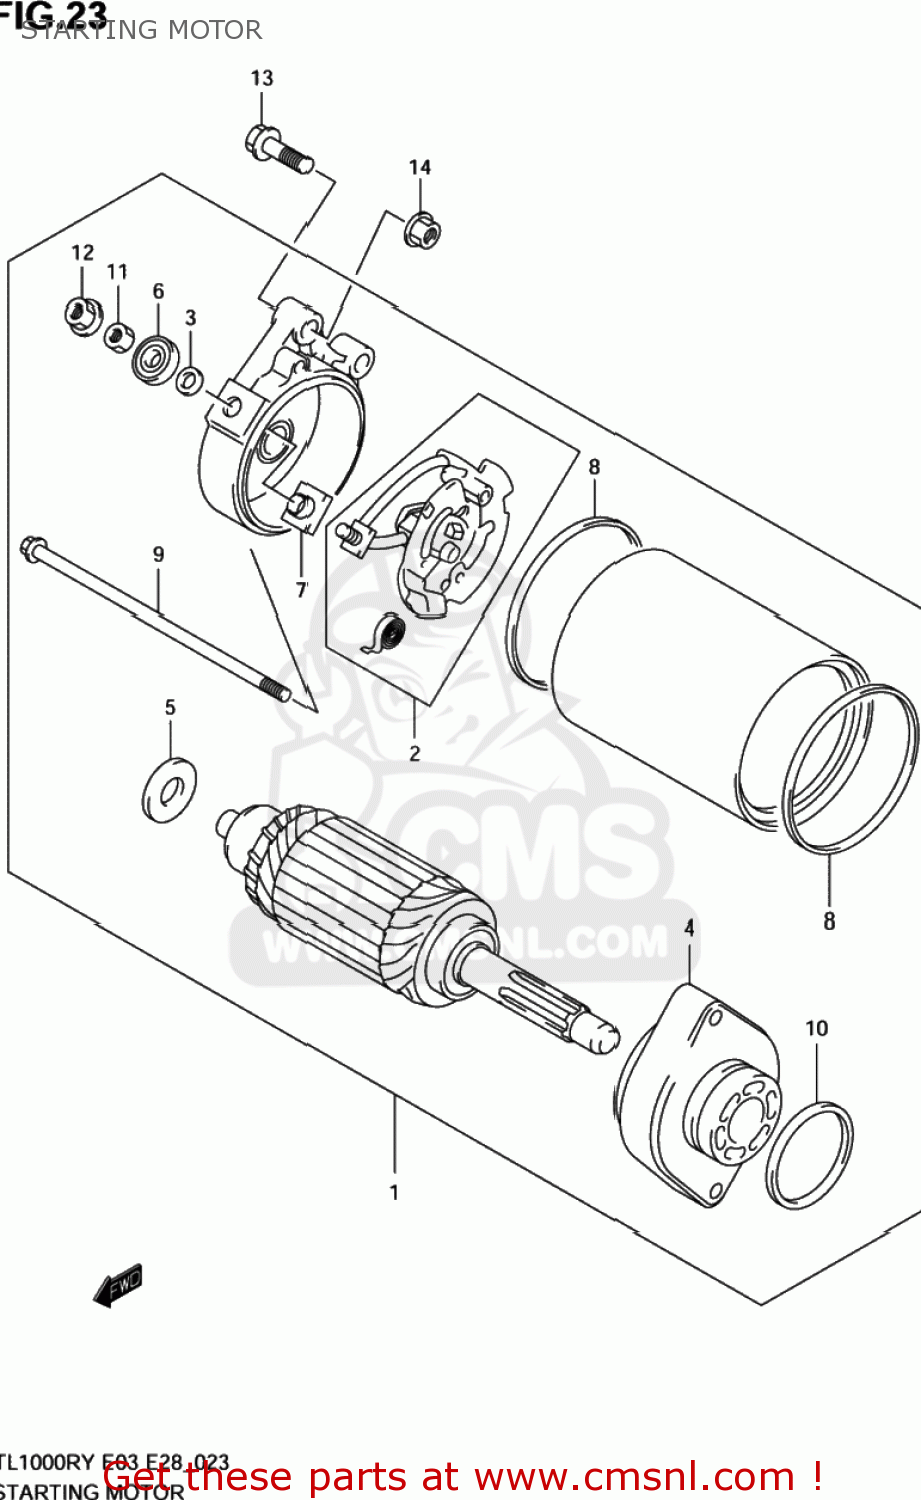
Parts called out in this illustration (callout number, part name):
1	MOTOR ASSY,STARTING
2	HOLDER SET,BRUSH
3	O RING
4	BRACKET SET
5	SHIM SET,STARTING MOTOR
6	BUSHING
7	BUSHING
8	O RING
9	BOLT
10	O-RING (D:2.1 ID:34.7)
11	NUT
12	NUT
13	BOLT
14	NUT
